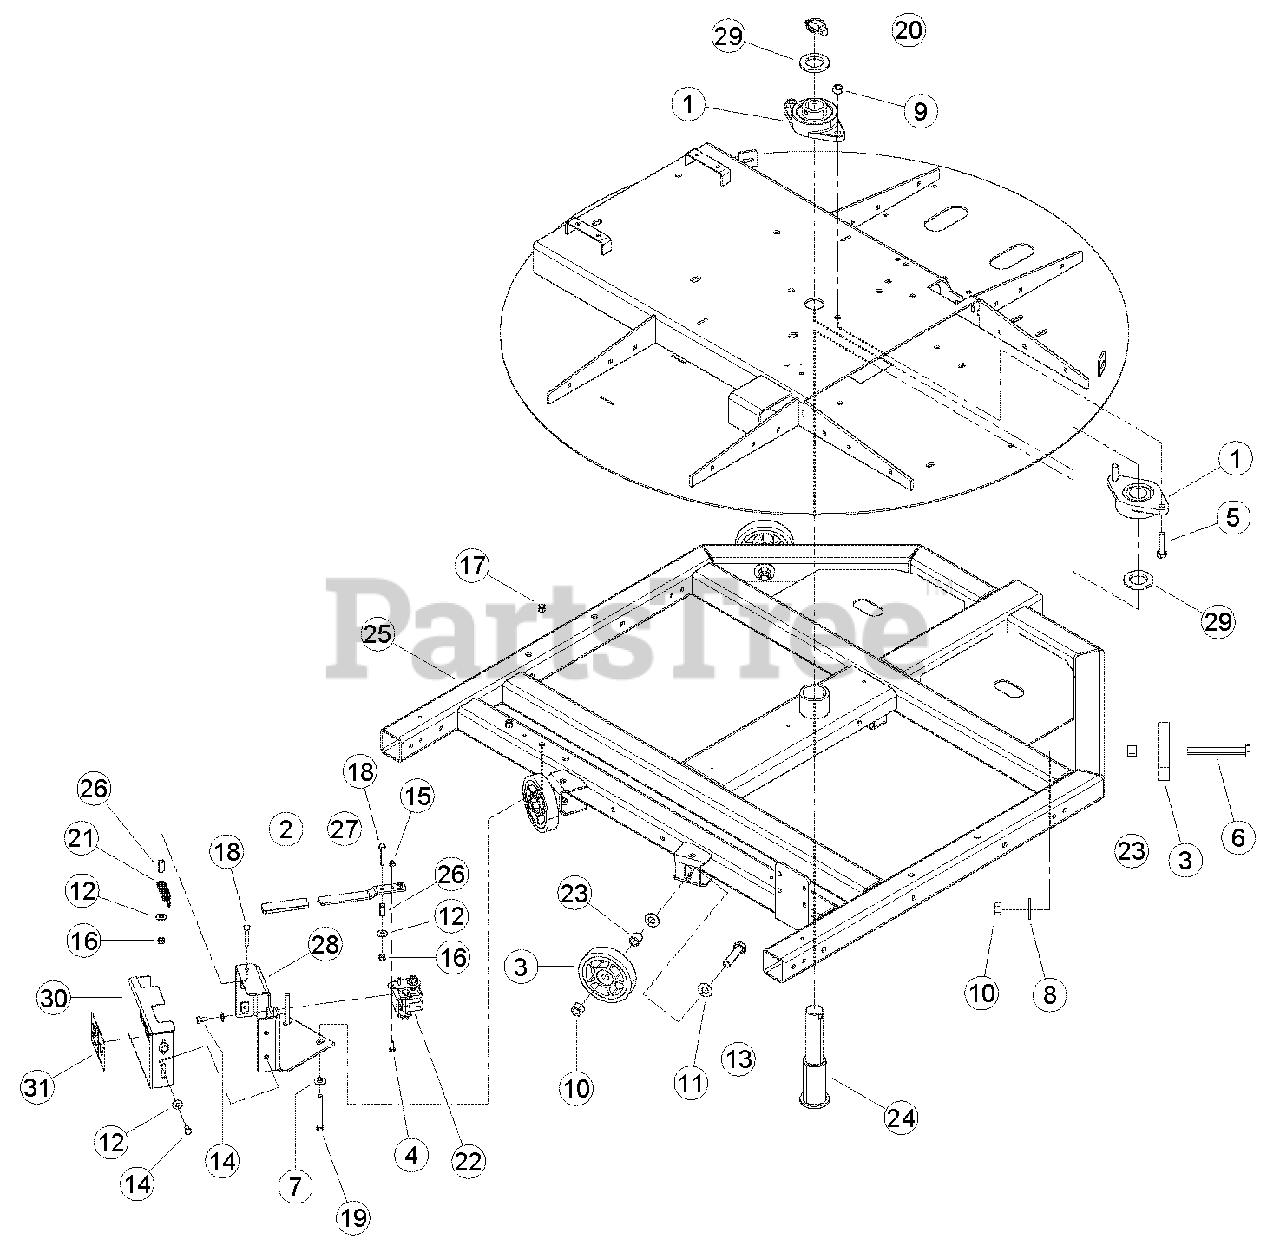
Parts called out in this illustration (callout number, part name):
1	BEARING, 1-1/2" 2-BOLT SET SCREW
2	GRIP, CLUTCH HANDLE
3	ROLLER, 5 X 1 X 5/8 NOFF AL
4	BOLT, 1/4 X 3/4 HEX HD GR5 ZP
5	BOLT, 1/2 X 2 HEX HD GR5 ZP
6	BOLT, 5/8 X 5 HEX HD GR5 ZP
7	WASHER, 3/8 FLAT ZP
8	WASHER, 5/8 FLAT ZP
9	NUT, 1/2 CENTERLOCK GRB ZP
10	NUT, 5/8 CENTERLOCK GR5 ZP
11	WASHER, 5/8 SAE FLAT ZP
12	WASHER, 5/16 FLAT ZP
13	BOLT, 5/8 X 2-1/2 HEX HD GR5 ZP
14	BOLT, 5/16 X 5/8 HEX HD GR5 ZP
15	NUT, 1/4 NE NYLOCK ZP
16	NUT, 5/16 NE NYLOCK ZP
17	NUT, 3/8 NE NYLOCK ZP
18	BOLT, 5/16-18 X 1-3/4 HCS GR5 ZP
19	BOLT, 3/8 X 3-1/4 HEX HD GR5 ZP
20	PIN, 7/16 X 1-3/4 LYNCH
21	SPRING, 3/4" OD EXTENSION
22	CALIPER, 210M BRAKE
23	SPACER, 7/8 X 3/4
24	PIN, CHIPPER PIVOT
25	WELDMENT, CHIPPER TRAILER
26	TUBE, 1/2" OD X 1.00
27	HANDLE, BRAKE
28	WELDMENT, BRAKE MOUNT
29	SPACER, 2.00 X 1.50 X 0.25
30	ASSEMBLY, BRAKE COVER, SERVICE PART
31	DECAL, BRAKE
